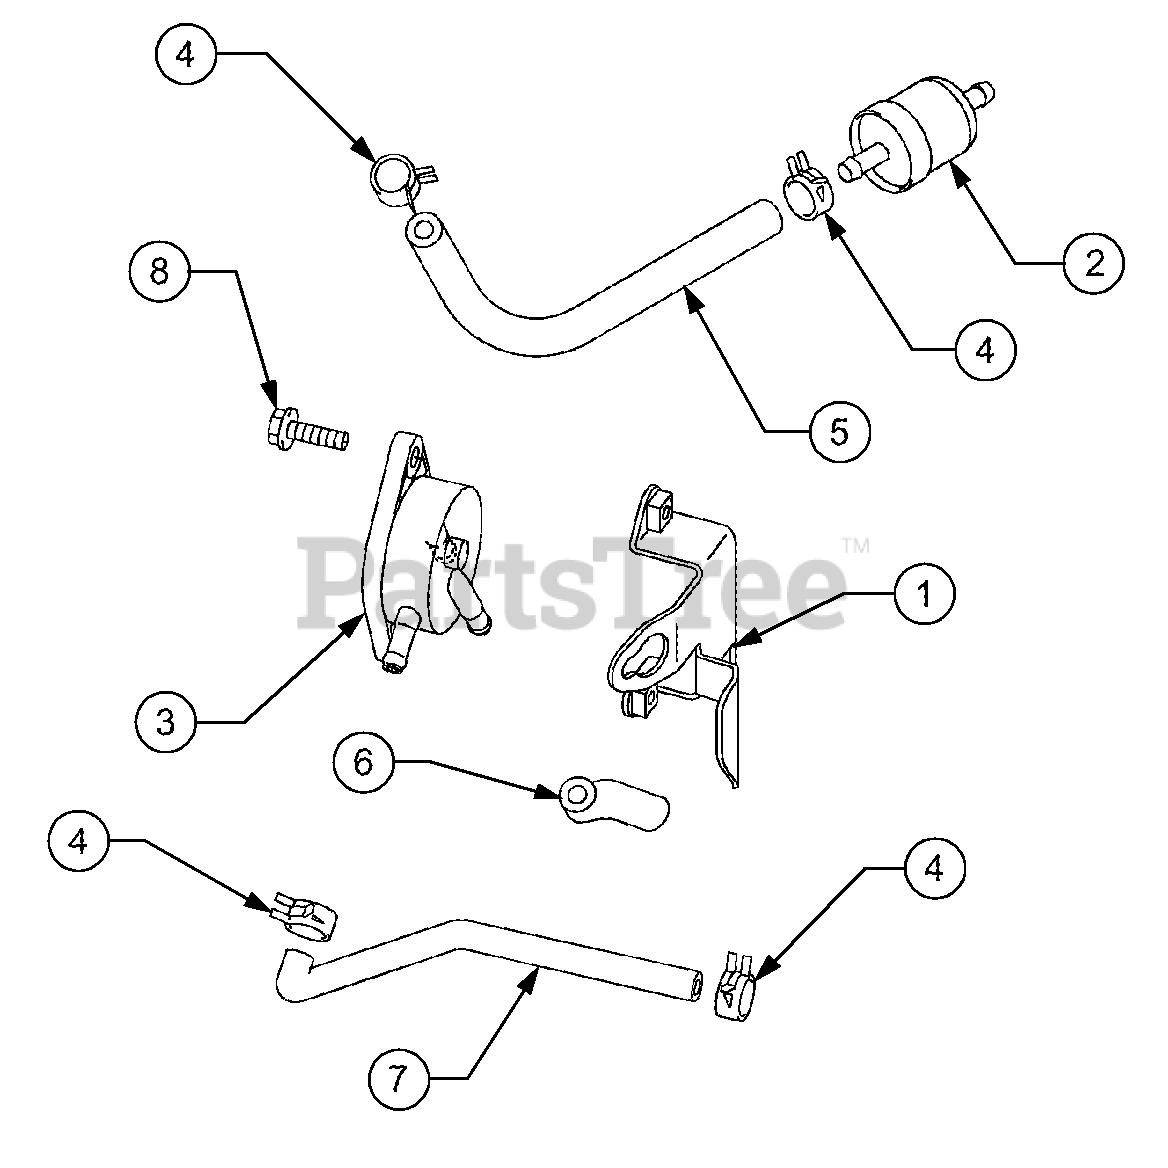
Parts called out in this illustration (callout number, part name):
1	Bracket, Comp
2	Filter, Fuel
3	Pump, Fuel
4	Clamp
5	Tube, 6.35x12.7x 160
8	Bolt, Flanged
